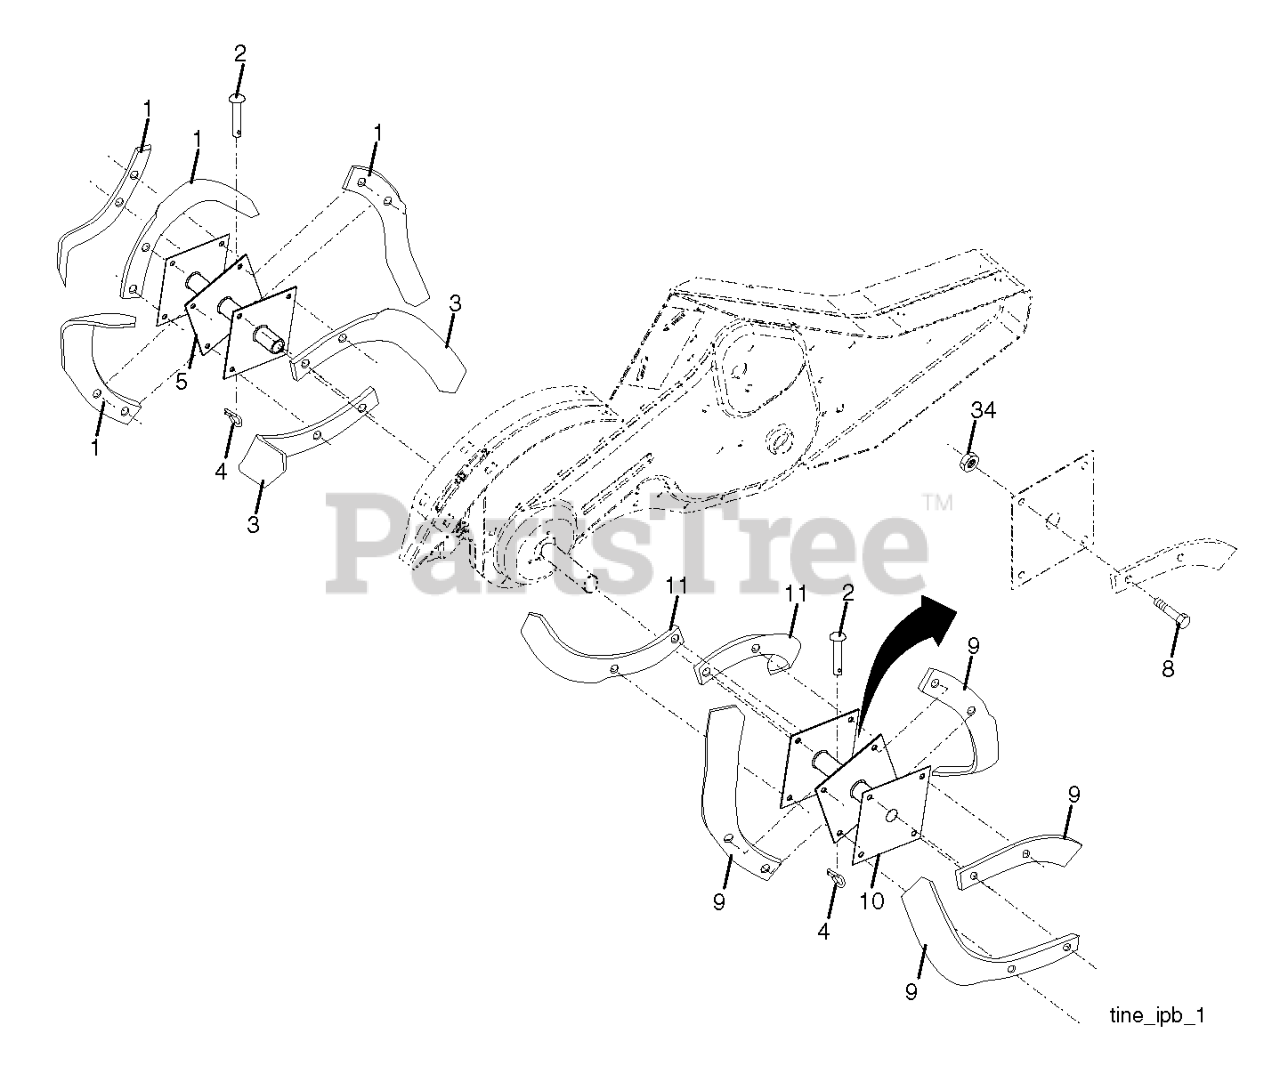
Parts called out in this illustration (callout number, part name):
1	TINE TI
2	PIN RETAINING SCREW
3	TINE.LH.12"(72L)
4	SPRING RETAINER
5	HUB.ASM.LH.BLACK
8	BOLT.HEX.001X20.37-24X1.ZINC
9	TINE TI
10	HUB.ASM.RH.17.TILLER.BLACK
11	TINE.RH.12"(72R)
34	NUT CROWNLOCK 3/8-24
